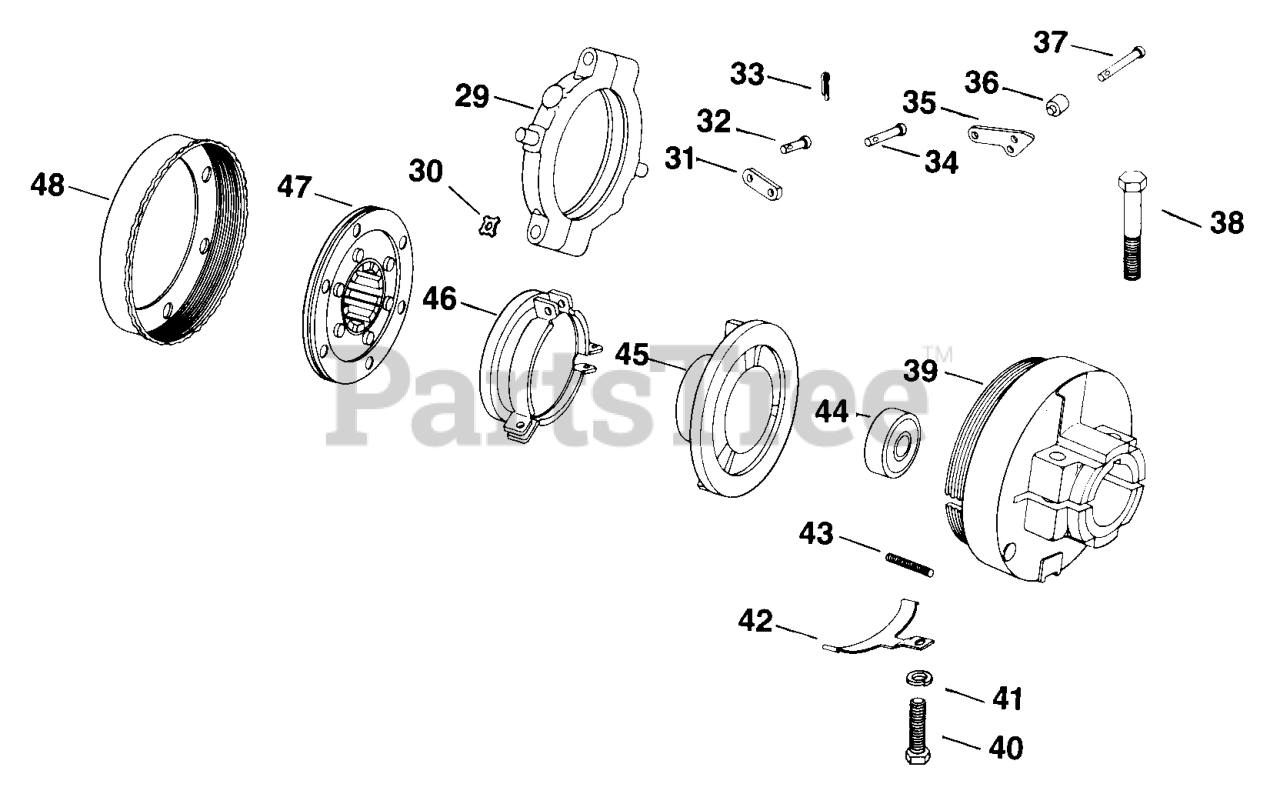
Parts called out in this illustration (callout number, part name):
30	LOCK - DISCONTINUED
31	LINK - DISCONTINUED
34	PIN - DISCONTINUED
35	LEVER - DISCONTINUED
36	ROLLER - DISCONTINUED
37	PIN - DISCONTINUED
39	HOUSING - DISCONTINUED
41	WASHER, SPRING LOCK 5/16"
41	WASHER, INT TOOTH LOCK 1/4"
43	SPRING - DISCONTINUED
44	BEARING
46	SLEEVE - DISCONTINUED
47	MEMBER - DISCONTINUED
48	RING - DISCONTINUED
